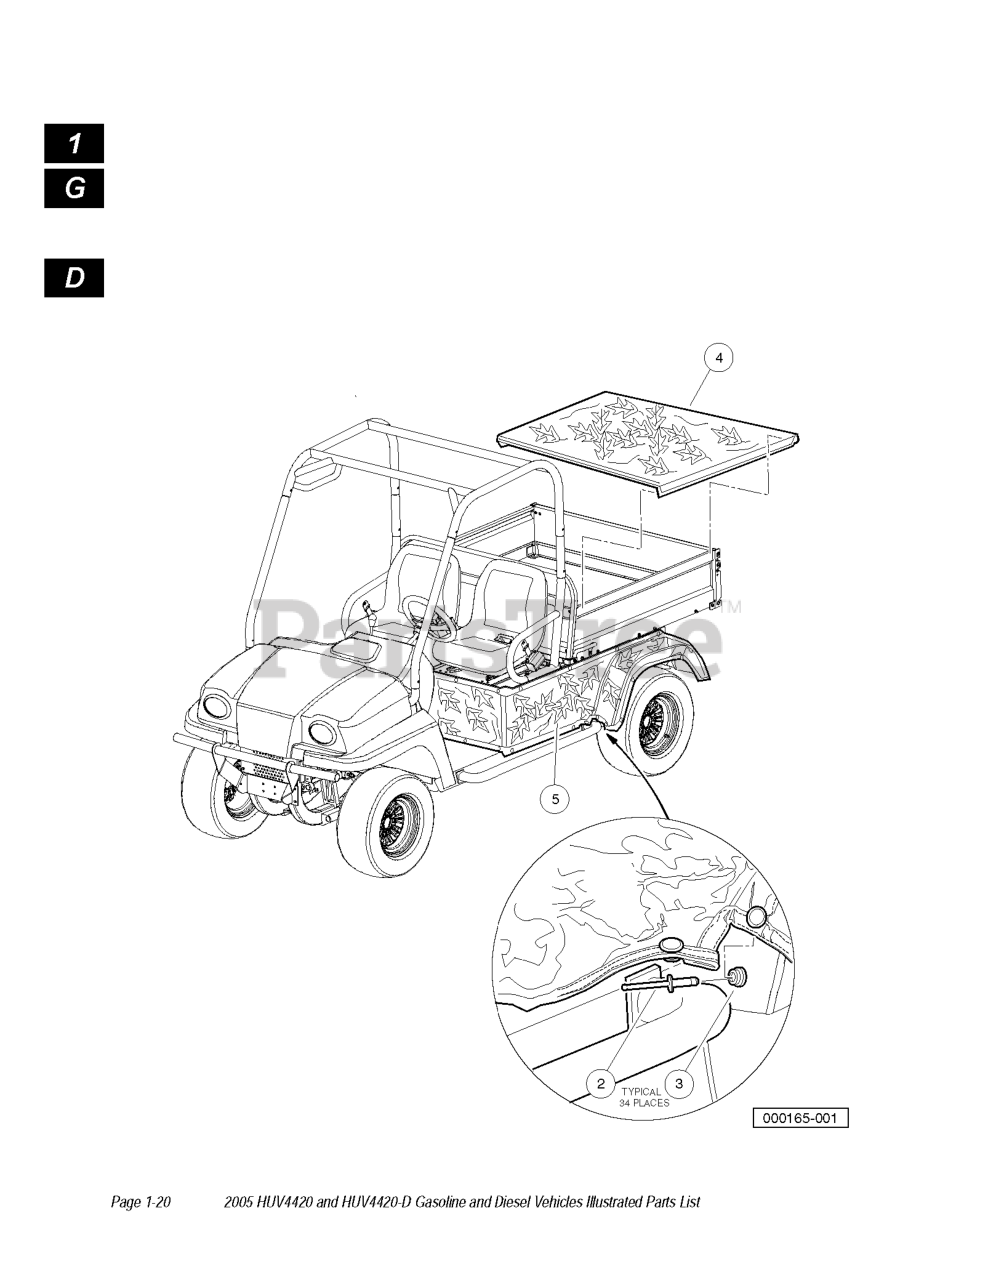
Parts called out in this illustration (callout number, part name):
1	KIT, CAMO COVER, 4X4
4	Cover, Camouflage Cargo Box
5	Wrap, Camouflage Rear Body
